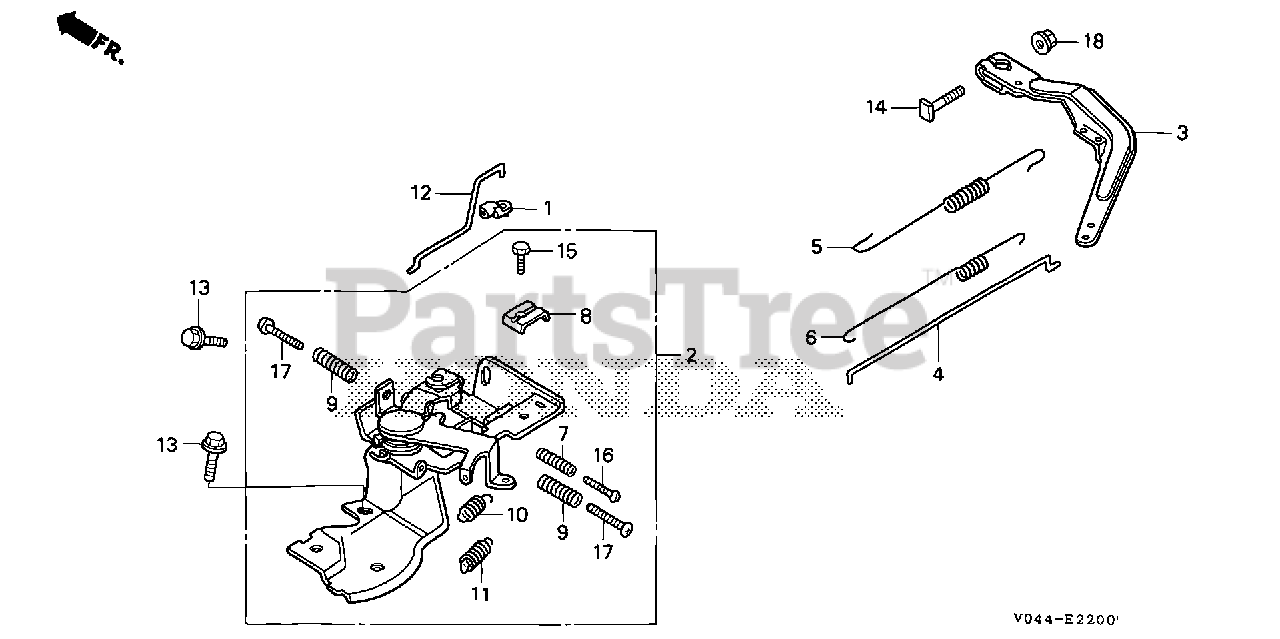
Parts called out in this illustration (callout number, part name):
1	JOINT, ROD
2	CONTROL ASSY.
3	ARM, GOVERNOR
4	ROD, GOVERNOR
5	SPRING, GOVERNOR
6	SPRING, THROTTLE RETURN
7	SPRING, CONTROL ADJUSTING
8	HOLDER, CABLE
9	SPRING, CONTROL ADJUSTING Use from Engine SN 2327377.
10	SPRING, CABLE RETURN
11	SPRING, CABLE RETURN
12	ROD, CHOKE
13	BOLT, FLANGE (6X12) (CT200)
14	BOLT, GOVERNOR ARM
15	BOLT, RECESSED (5X16)
16	SCREW, PAN (4X20)
17	SCREW, PAN (5X20)
18	NUT, FLANGE (6MM)
